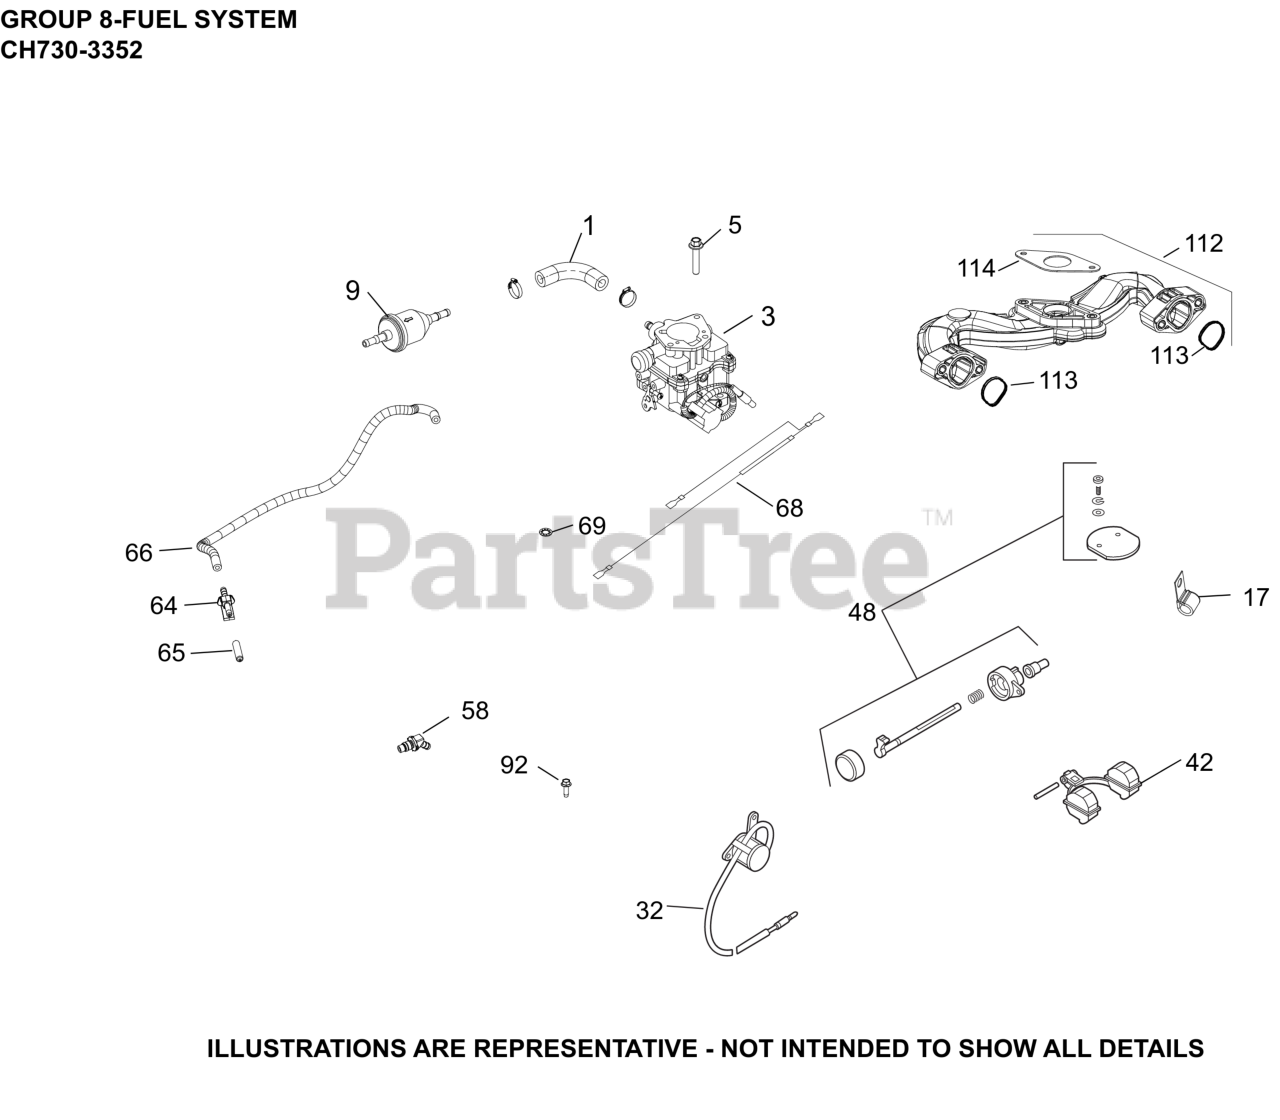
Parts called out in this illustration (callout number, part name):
1	HOSE,LW PERM.FUEL 24.00"-USE 25 111 81-S
3	KIT, CARBURETOR COMPLETE
5	SCREW, FLG M6X1.0X25
9	FILTER, FUEL
17	CLIP, CABLE
32	KIT, SOLENOID
42	KIT, REPAIR FLOAT
48	KIT, REPAIR CHOKE
58	KIT, 45 DEG. FITTING
64	CONNECTOR, EVAPORATIVE
65	CAP, MASKING
66	HOSE, EVAPORATIVE 20"- (#24326143S)
68	LEAD, GROUND
69	WASHER, INT TOOTH LOCK 1/4"
92	SCREW, THREAD FORMING
112	INTAKE MANIFOLD W/GASKETS
113	O-RING, INTAKE PORT
114	GASKET, CARBURETOR (PIM, CH)
NI	KIT, HIGH ALT (4000-8000 FT)
NI	KIT, HIGH ALT (8,000+ FT)
NI	KIT, REPAIR CARBURETOR
